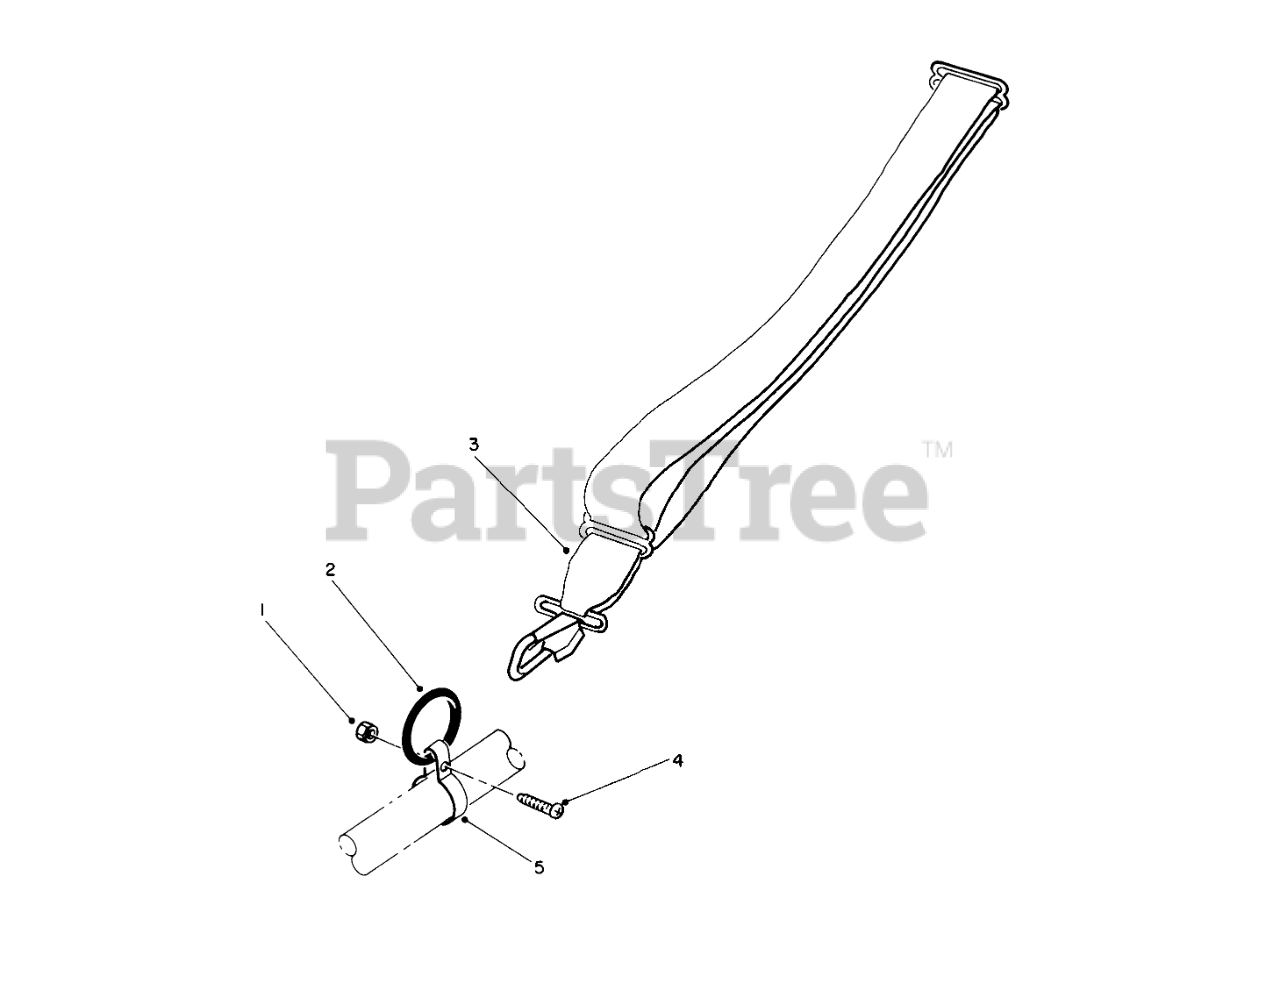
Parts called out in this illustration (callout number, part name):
1	Nut
2	Ring
3	Harness
4	Clamp & Ring Kit (Incl. Ref. #1, 2, 4, & 5)
5	Clamp
